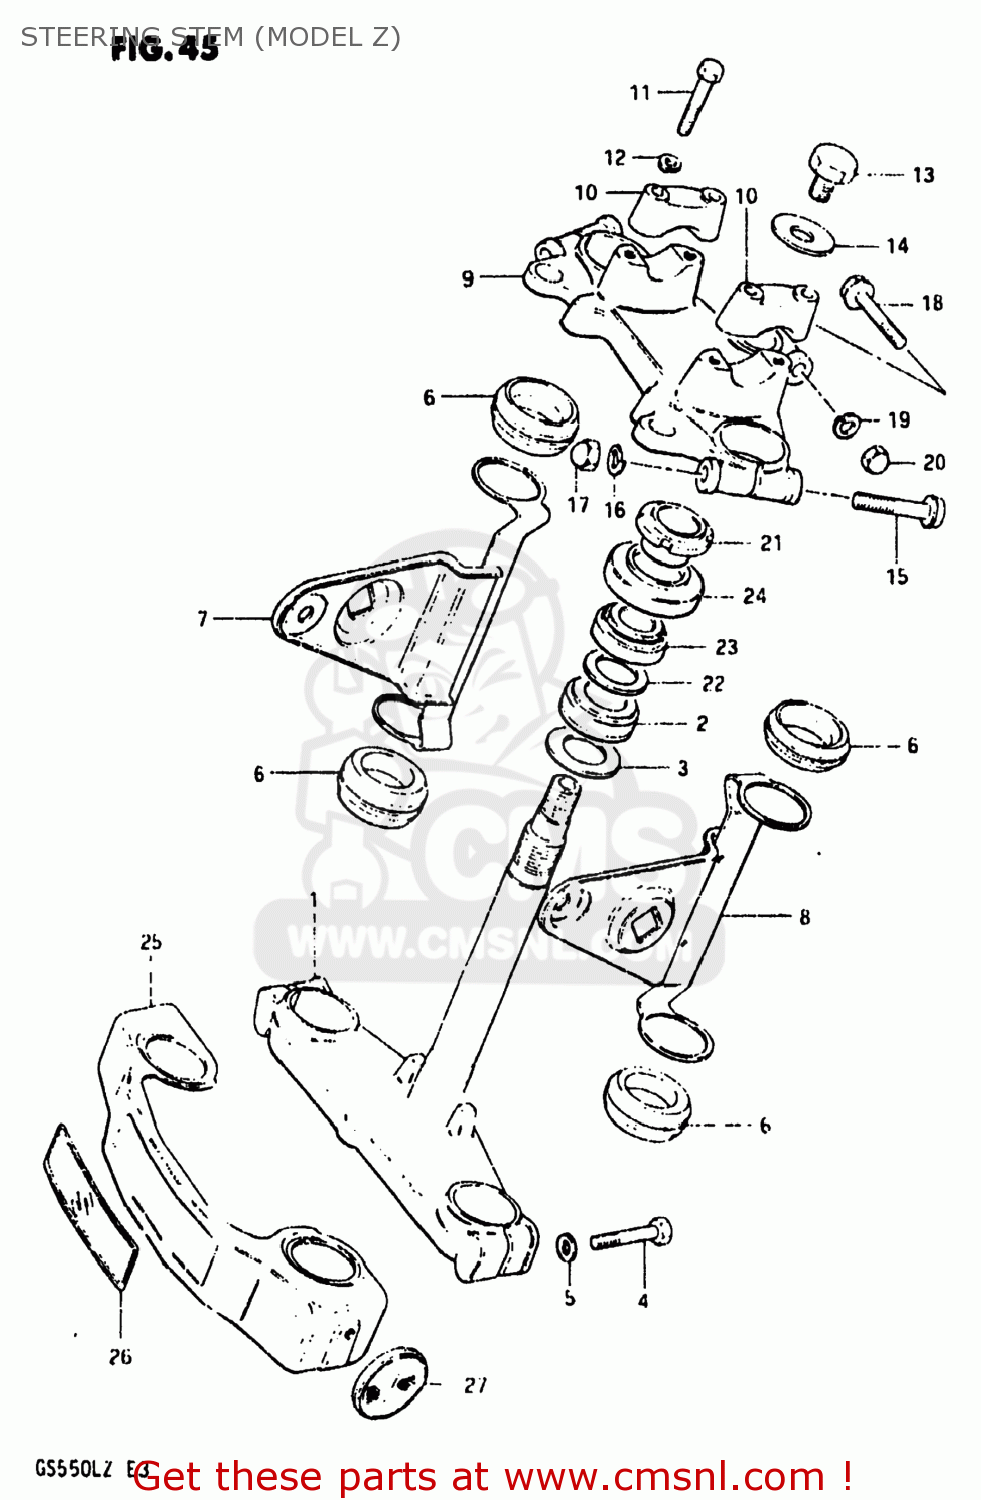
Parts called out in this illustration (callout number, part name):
1	STEM,STEERING
2	BEARING
3	WASHER,THRUST
4	BOLT 8X45
5	WASHER,LOCK,8.
6	CUSHION,HEADLAMP BRACKET
7	BRACKET,HEADLAMP,RIGHT
8	BRACKET,HEADLAMP,LEFT
9	HEAD,STEERING STEM
10	HOLDER,HANDLE UPR
11	BOLT
12	LOCK WASHER
13	BOLT(12X20)
14	WASHER
15	BOLT 10X55
16	LOCK WASHER
17	NUT
18	BOLT
19	LOCK WASHER
20	NUT
21	NUT,STEERING STEM
22	WASHER(18.5X24X1)
23	TAPER,ROLLER BEARING
24	DUST SEAL,STEERING UPR
25	COVER,FRONT FORK
26	EMBLEM,FR FORK COVER
27	REFLEX REFLECTOR,RR
